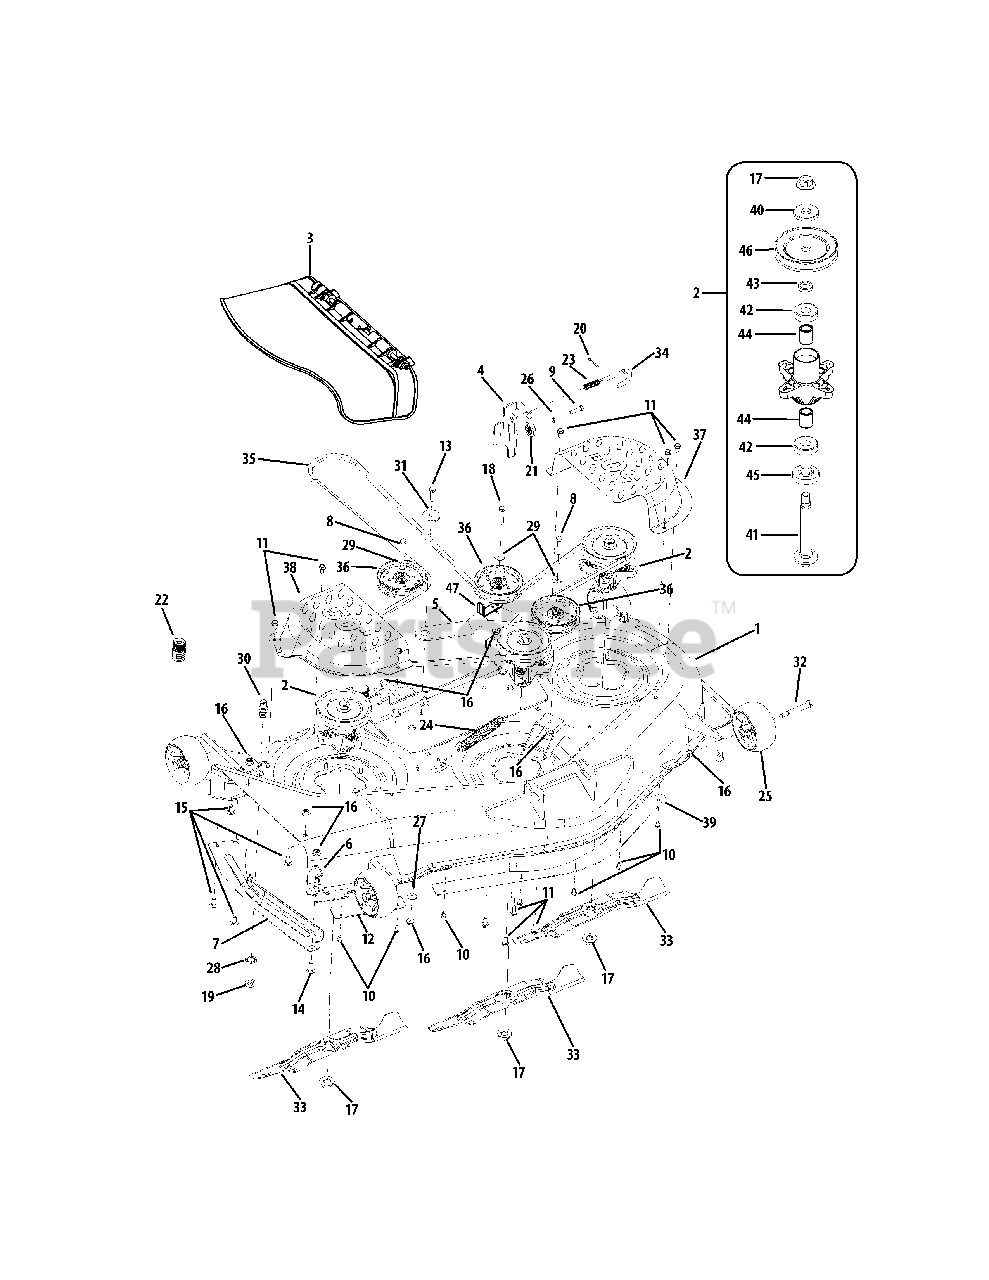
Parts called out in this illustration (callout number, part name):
1	Deck Housing
2	Spindle Assembly
3	Discharge Chute Assembly
4	Deck Hanger Bracket
5	Idler Arm
6	Stop Bracket
7	Finger Guard
8	Hex Cap Screw, 3/8-16 x 1.75
9	Hex Cap Screw, 5/16-18 x 1.25
10	Hex Washer Head Screw, 1/4-20 x .5
11	Hex Washer Head Screw, 5/16-18 x .750
12	RH Skirt
13	Hex Cap Screw, 3/8-16 x 1.25
14	Hex Screw, 3/8-16 x 1.00
15	Carriage Screw, 3/8-16 x .75
16	Hex Insert Flange Lock Nut, 3/8-16
17	Hex Flange Nut, 5/8-18
18	Hex Cap Screw, 3/8-16 x 2.00
19	Hex Nut, M16-1.5
20	Cotter Pin, 1/8 x 1.25
21	Deck Adjustment Gear
22	Water Nozzle Adapter
23	Compression Spring, .535 x 1.751
24	Extension Spring, .94 x 6.74
25	Deck Ball Wheel, 5.0
26	Lock Washer, 5/16
27	Bell Washer, .45 x 1.0 x .062
28	Internal Tooth Lock Washer, 5/8
29	Flat Washer, .38 x .93 x .110
30	Deck Wash Nozzle
31	Shoulder Spacer, .884 x .190
32	Shoulder Screw, .5 x 2.5 x 3/8-16
33	Blade, 2 in 1, 17.9
34	Deck Hanger Rod
35	V-Belt Type A Sec x 134
36	Idler Pulley, 4.25 Dia
37	Belt Cover, LH
38	Belt Cover, RH
39	Center Skirt (U.S.)
40	Flat Washer, .76 x 1.50 x .12
41	Spindle Shaft, 5.75
42	Ball Bearing
43	Spacer, .79 x 1.25 x .175
44	Spacer, .80 x 1.10 x 1.32
45	Spacer, .79 x 1.82 x .55
46	V-Type Pulley, 5.39
47	Bracket, Belt Guard
